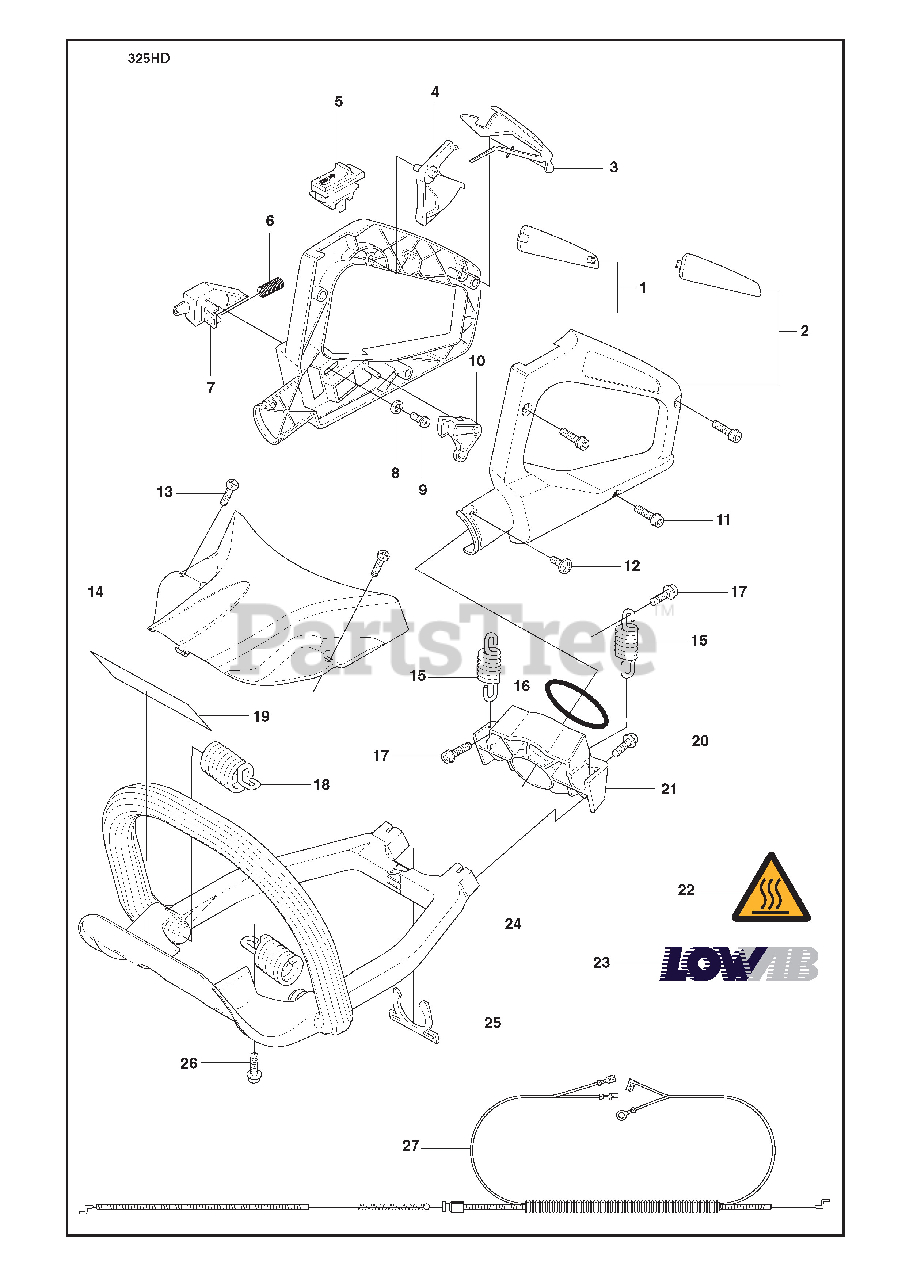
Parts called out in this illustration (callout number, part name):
1	REAR HANDLE COMPLETE
2	HANDLE PART
3	THROTTLE LOCK
4	THROTTLE TRIGGER
5	STOP BUTTON
14	HEAT PROTECTOR EXHAUST PIPE
15	VIBRATION ABSORBER
18	VIBRATION ABSORBER
